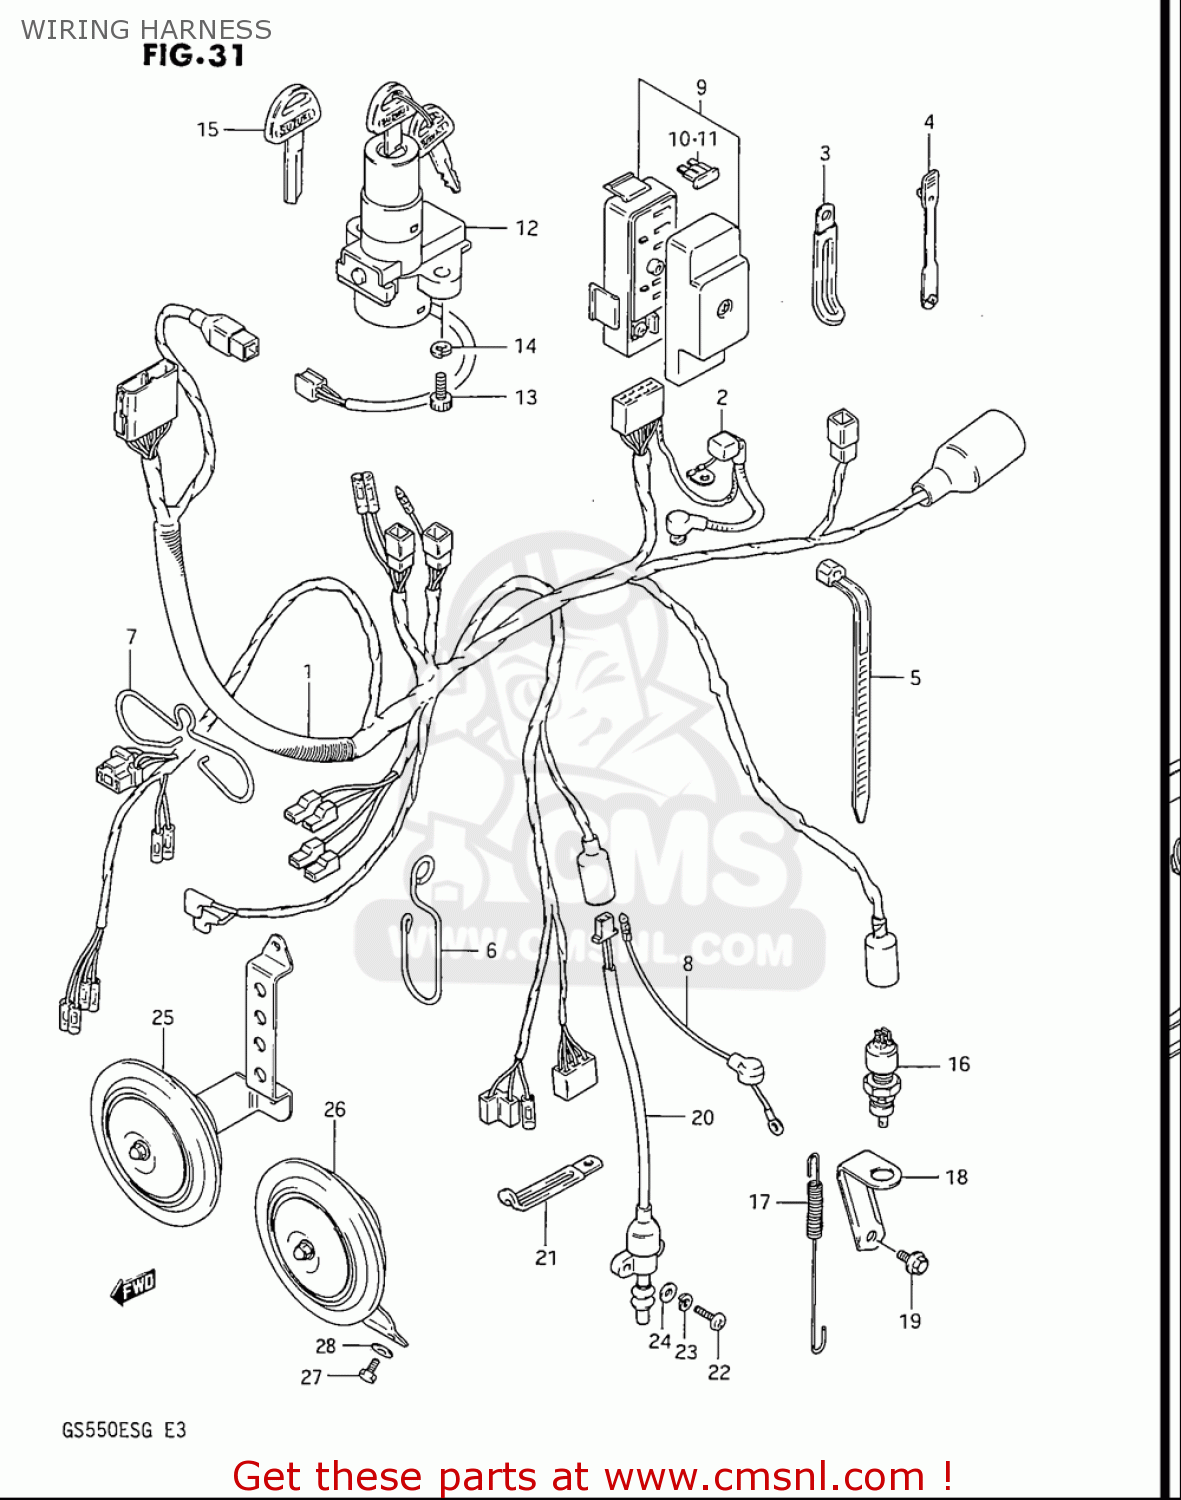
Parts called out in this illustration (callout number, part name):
3	CLAMP(L:65)
4	CLAMP,L:88
5	CLAMP(L:95)
6	GUIDE,WIRING HARNESS
7	BOOT,WIRING HARNESS
8	WIRE,WATER TEMPERATURE
9	FUSE BOX ASSY
10	FUSE(10A)
11	FUSE(15A)
12	IGNITION SWITCH/STEERING LOCK
13	BOLT
14	WASHER,LOCK
15	KEY,BLANK
16	SWITCH ASSY,STOP LAMP
17	SPRING
19	BOLT
20	SWITCH ASSEMBLY,SIDE STAND
21	CLAMP(L:80 T:1.0)
22	SCREW
23	LOCK,WASHER
24	WASHER
27	BOLT
28	WASHER,LOCK
